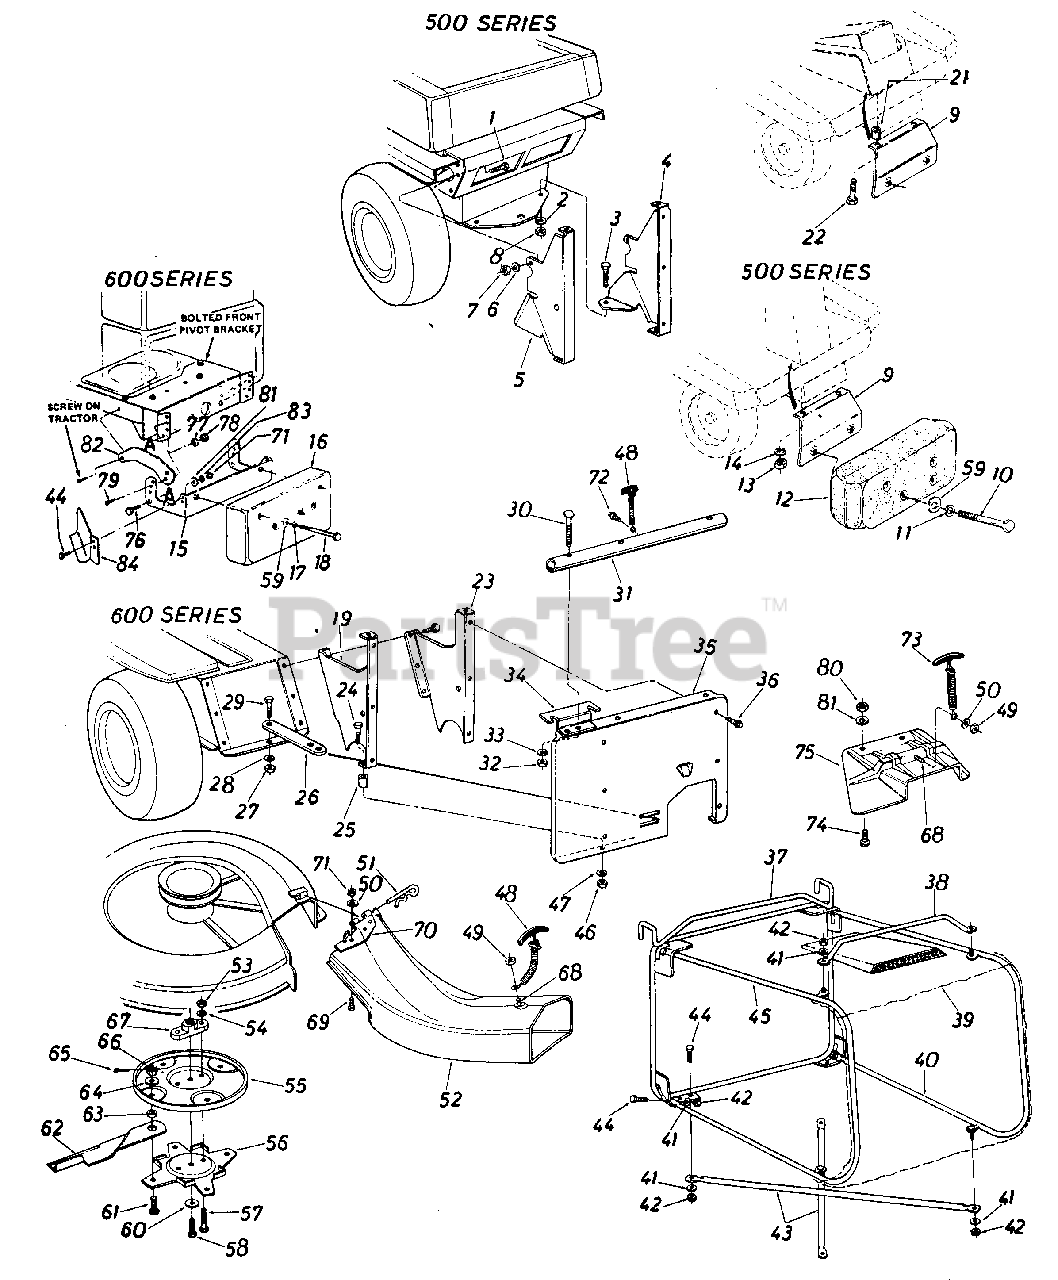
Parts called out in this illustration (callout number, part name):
1	Hex Bolt 5/16-18 x 1.00" Lg.*
2	L.-Wash. 5/16" I.D.*
3	Hex Bolt 5/16-18 x 1. 00" Lg.*
4	Catcher Support Brk't.-R.H.
5	Catcher Support Brk't.-L.H.
6	L.-Wash. 5/16" I.D.*
7	Hex Nut 5/16-18 Thd.*
8	Hex Nut 5/16-18 Thd.*
9	Counterweight Support Brk't. Ass'y.
10	Hex Bolt 3/8-16 x 4.5" Lg.*
11	Belleville Wash. .400" I.D. x .88" O.D.
12	Counterweight 38 lbs.
13	Hex Nut 5/16-18 Thd.*
14	L.-Wash. 5/16" I.D.*
15	Counterweight Support Brk't. Ass'y.
16	Counterweight 38 lbs.
17	Belleville Wash. .400" I.D. x .88" O.D.
18	Hex Bolt 3/8-16 x 4.5" Lg.*
19	Catcher Support Brk't.-L.H
21	Spacer .380" I.D. x 1.00" 0.D. x .320" Lg.
22	Not Part of Kitt
23	Catcher Support Brk't.-R.H.
24	Hex Bolt 5/16-18 x 1.50" Lg.*
25	Spacer .380" I.D. x .47" O.D. x 1.00" Lg.
28	L.-Wash. 1/2" I.D.
29	Hex Bolt 1/2-20 x 1.00" Lg.*
30	Curved Carriage Bolt 5/16-18 x 1.75" Lg.
33	L.-Wash. 5/16" I.D.*
34	Grass Catcher Support Plate
35	Rear Discharge Panel
36	Hex Wash. Hd. Self Tap. Scr. 1/4 x 20 x .50
37	Grass Catcher Frame Ass'y. .30"
40	Catcher Side Frame Ass'y. R.H.
41	Spring-Wash. .270" I.D. x .57" O.D. x .025
42	Hex L.-Nut 1/2-20 Thd.
43	Bottom Cross Brace 26.62
44	Hex Bolt 1/4-20 x .62" Lg.*
47	L.-Wash. 5/16" I.D.*
48	Hook Latch Ass'y.
49	Hex L.-Nut 1/4-20 Thd
50	Fl.-Wash. 1/4" I.D.*
51	Not Part of Kit
52	R.D. Banana Chute Assy.
53	Hex Nut 5/16-24 Thd.*
54	L.-Wash. 5/16" I.D.*
55	Upper Blade Disc
58	Hex Bolt 3/8-24 x 1.00" Lg.
59	Fl.-Wash. .39" I.D. x 1.12" 0.D.
60	Bell.-Wash. .39" I.D. x 1.38" O.D.
61	Shld. Bolt .500" Dia x .360 Spec.
62	30" Blade Tip
63	Spacer .505" I.D. x .750" O.D. x 1.25" Lg.
64	Fl.-Wash. .500" I.D. x 1.25" O.D.
65	Cotter Pin 3/32" Dia. x 1.00" Lg.
66	Hex Slotted Nut 1/2-20 Thd.
67	Blade Adapter
68	Hex Bolt 1/4-20 x .50" Lg.*
69	Truss Mach. Scr. 1/4-20 x .50" Lg.*
72	Hex "AB"-Tap Scr. 1/4 x .62" Lg.
73	Hook Latch Ass'y. x 7.0" Lg.
74	Truss Mach. Scr. 1/4-20 x .50" Lg.
75	R.D. Chute Extension
76	Hex Bolt 7/16-14 x 1.00" Lg.*
77	L.-Wash. 7/16" I.D.*
78	Hex Nut 7/16-14 Thd.*
79	Self-Tap Scr. 5/16-18 x 1.0" Lg.
80	Hex L. Nut 1/4-20 Thd.
81	Fl. Wash. .281" I.D. x .50" O.D. x .063
82	Tie Strap
83	L-Wash. 1/4" I.D.*
84	Exhaust Deflector
